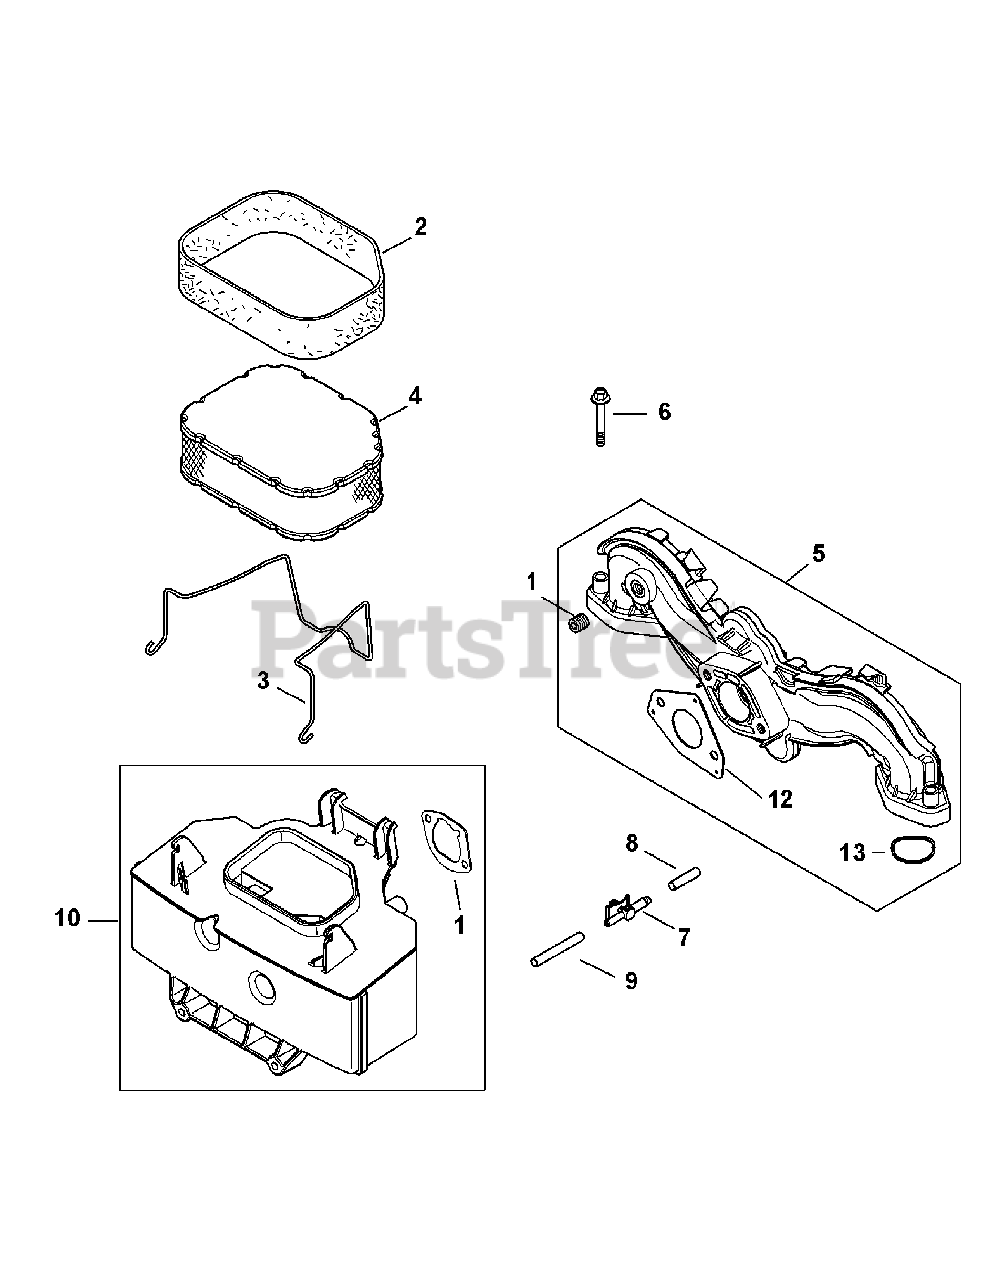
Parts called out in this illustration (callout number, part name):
1	Air Cleaner Base Gasket
2	Pre-Cleaner Element
3	Air Cleaner Element Latch
4	Air Filter Element
5	Intake Manifold Kit
6	Flange Screw, M6 x 1.0 x 40
7	Evaporative Connector
8	Evaporative Mask
9	Evaporative Hose, 20"
10	Air Cleaner Base
11	Pipe Plug, 1/8
12	Carburetor Gasket
13	Intake Port O-Ring
